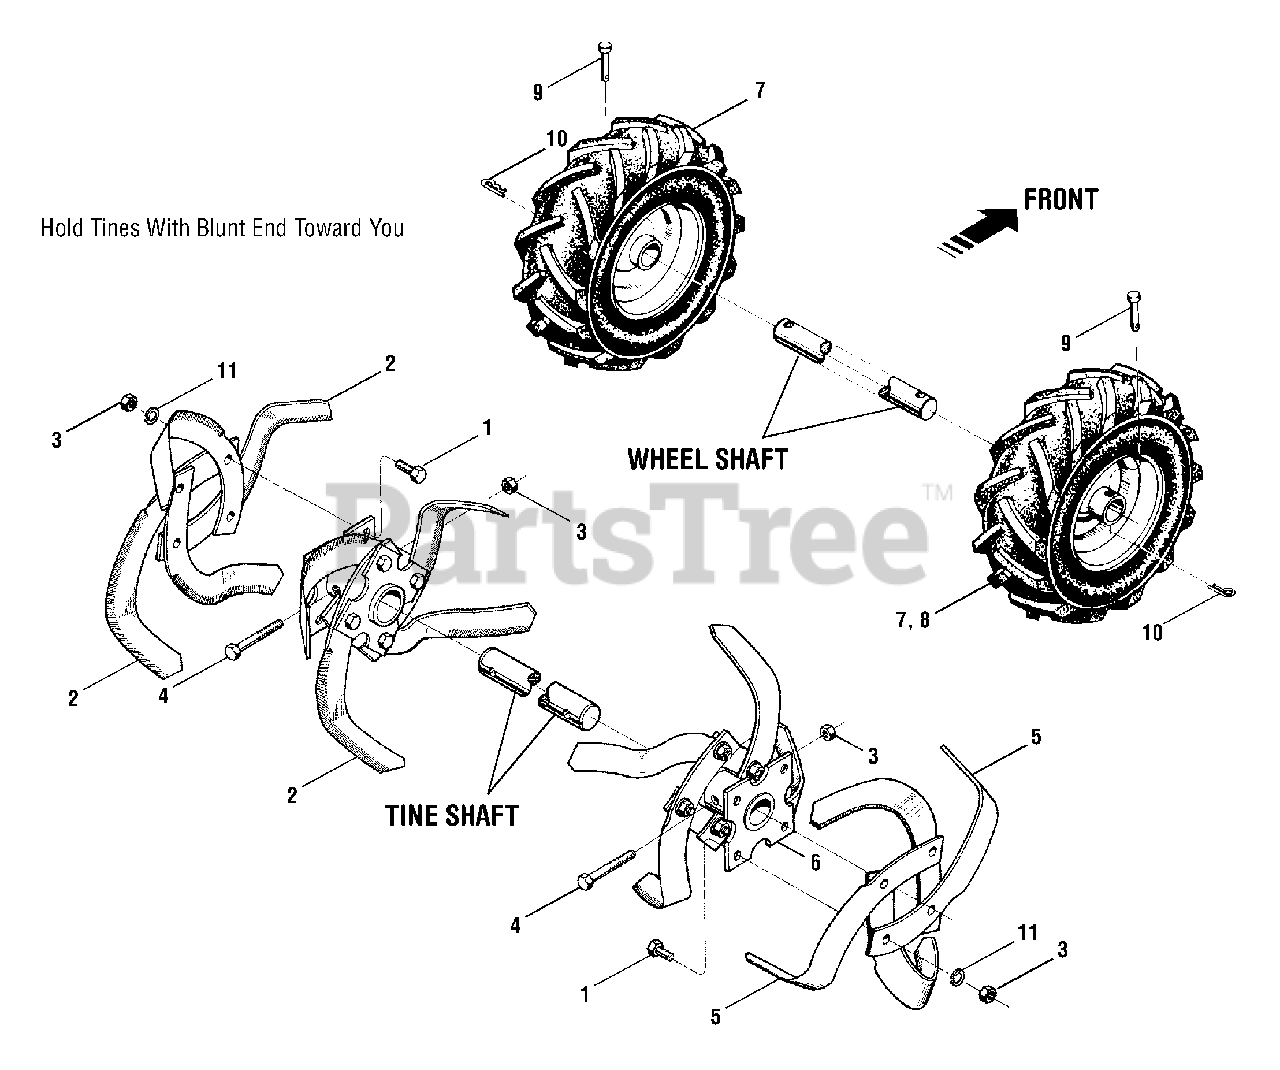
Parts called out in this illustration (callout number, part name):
1	Hex Hd. Screw, 3/8-16 x 1-1/4, Grade 5
2	Single Bolo Tine - Right Hand
3	Hex Lock Nut, 3/8-16
4	Hex Hd. Screw, 3/8-16 x 1-3/4
5	Single Bolo Tine - Left Hand
6	Tine Holder
7	Wheel & Tire Ass'y - Left/Right Side
8	Wheel & Tire Ass'y - Right Side Only
9	Clevis Pin, .312" x 1-3/4"
10	Hair Pin Cotter
11	Lock Washer, 3/8
